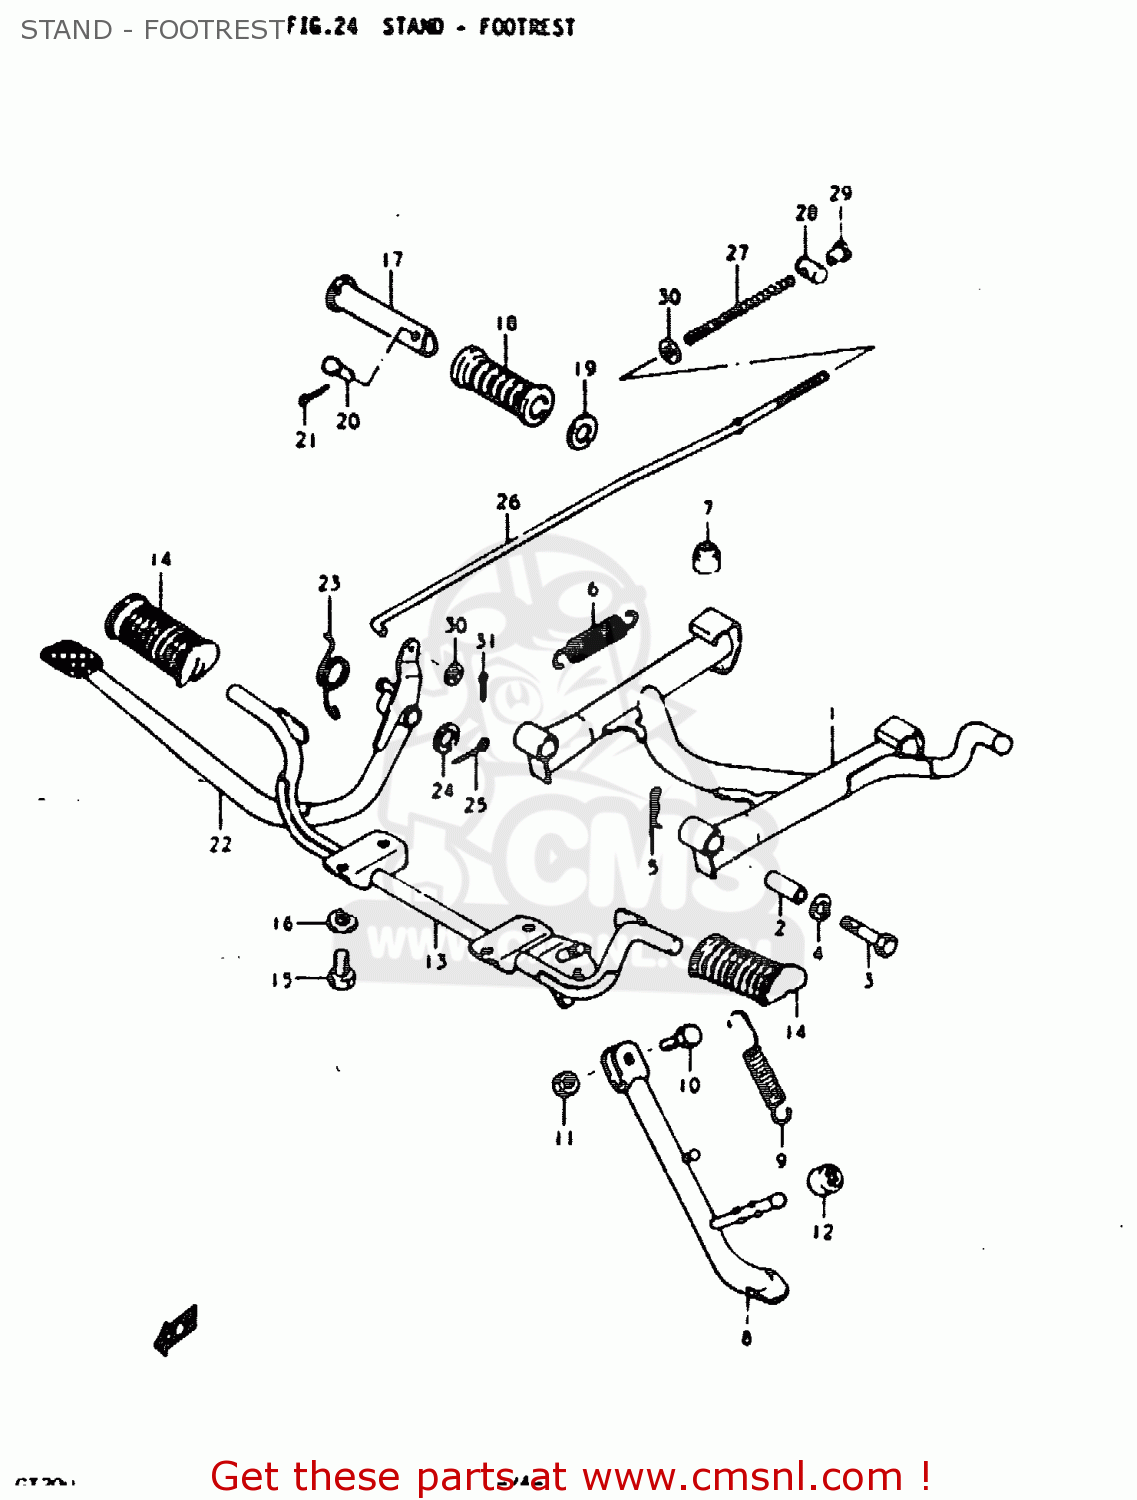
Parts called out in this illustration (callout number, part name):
1	STAND, CENTER
2	SPACER(10.5X16X30)
3	BOLT 10X52
4	LOCK WASHER
5	CLIP
6	SPRING
7	CUSHION
8	STAND, PROP
9	SPRING
10	BOLT
11	NUT
12	CUSHION
13	BAR, FRONT FOOTREST
14	RUBBER,FR FOOTREST
15	BOLT
16	LOCK WASHER
17	BAR,FOOTREST RUBBER
18	RUBBER,PILLION FOOTREST
19	WASHER (19.5X32X2)
20	PIN
21	PIN 20X20
22	PEDAL,BRAKE
23	SPRING
24	WASHER(15.5X26X2.3)
25	COTTER PIN
26	ROD ASSY, REAR BRAKE
27	SPRING
28	PIN
29	NUT
30	WASHER
31	PIN 20X20
